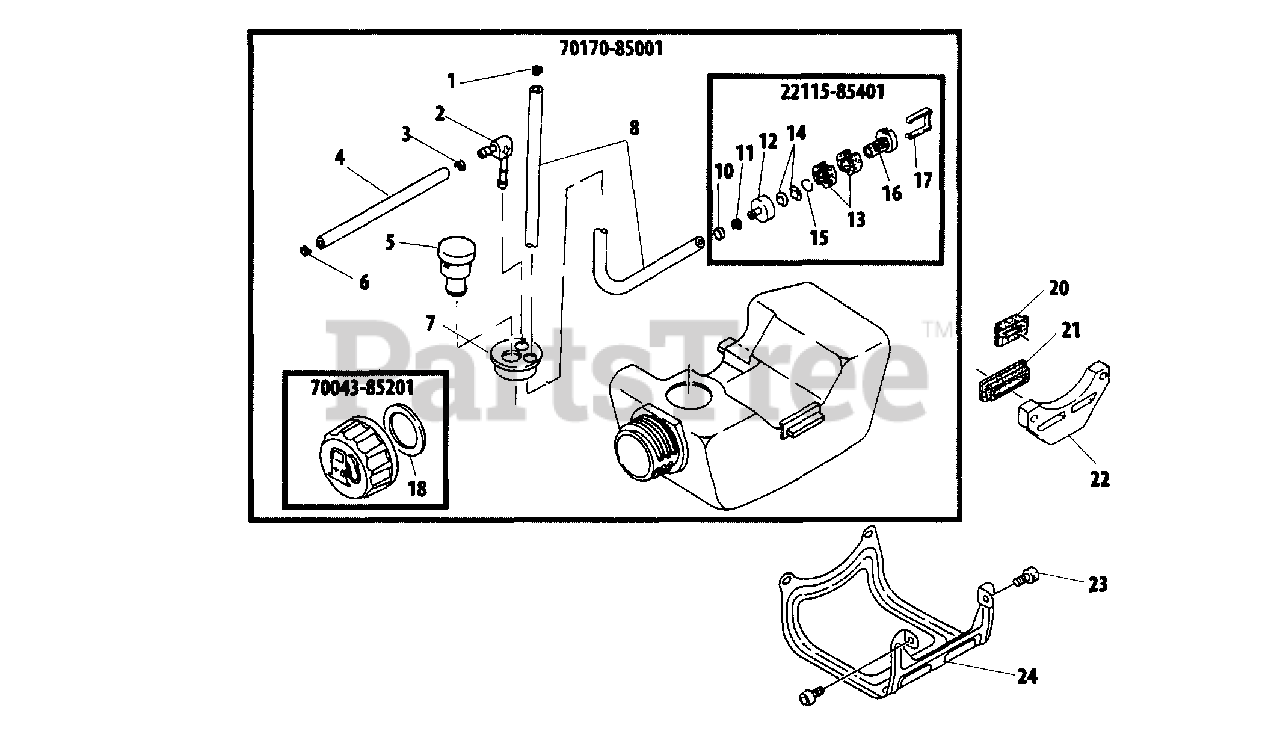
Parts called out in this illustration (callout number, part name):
1	RING, RETAINING
2	CONNECTOR, PIPE
3	RING, RETAINING
4	PIPE - RETURN
5	VENT, FUEL TANK
6	RING, RETAINING
7	GROMMET
8	PIPE - FUEL
10	VENT, FUEL TANK
11	RING, RETAINING
12	WEIGHT, FUEL FILTER
13	FILTER, FUEL
14	STRAINER
15	RING, RETAINING
16	CASE, FILTER
17	CLIP, FILTER
18	GASKET, CAP
20	CUSHION, TANK
21	CUSHION, TANK
22	BRACKET, FUEL TANK
23	SCREW - 5X12
24	GUARD, FUEL TANK
